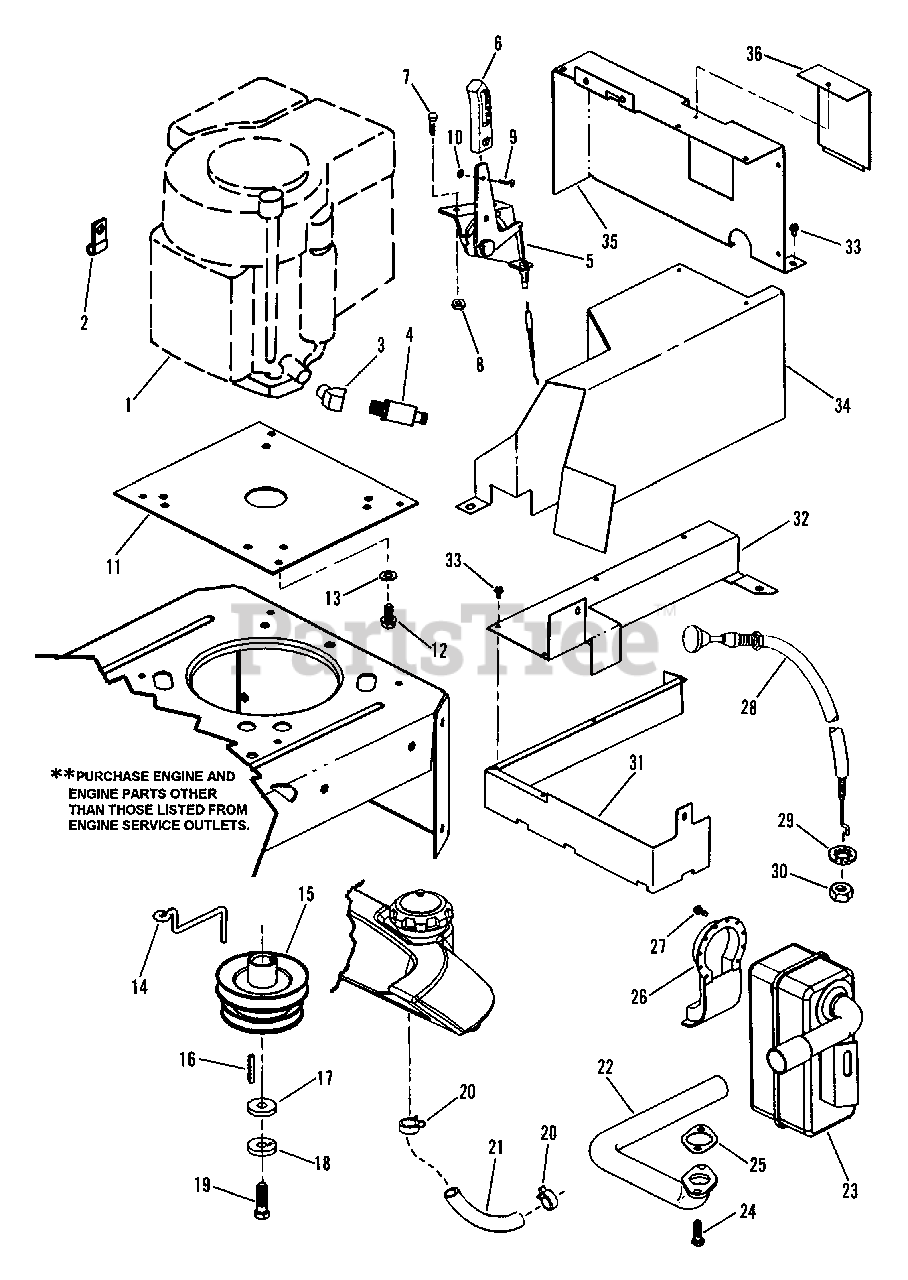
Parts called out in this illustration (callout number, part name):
2	WIRE CLIP, 7/16"
3	FITTING, Oil Drain 90° (Briggs 14HP)
4	ASSEMBLY, Oil Valve
5	CONTROL, Throttle (Kohler 15HP) 52.5"
6	LEVER, Throttle Control
7	SCREW, #10-32 x 5/8" Hex Washer Head, Grade 5
8	NUT, #10-32 Nyloc
9	SCREW, #8-32 x 3/8" Machine
10	NUT, #8-32 Hex
11	PLATE, Engine
12	SCREW,3/8-16 x1" Hex Washer Head (Briggs)
13	WASHER, 5/16 Split Lock (Kohler)
14	GUIDE, Belt
15	PULLEY, Engine (Small Pulley - Down)
16	KEY, 1/4" Square x 2"
17	SPACER, Clutch
18	WASHER, 7/16" Split Lock
19	SCREW, 7/16-20 x 1-1/2" Hex Head Cap, Grade 5
20	CLAMP, Fuel Hose
21	HOSE, Fuel 1/4" I.D.x 20"
22	PIPE, Exhaust (Briggs 14HP)
23	MUFFLER, Low Tone
24	SCREW, 5/16-18 x 3/4" Hex Head Cap, Grade 5 (Briggs 14HP)
25	GASKET, Exhaust (Briggs 14HP)
26	DEFLECTOR, Muffler (42" & 48" Decks only)
27	SCREW, #8-18 x 1/2" (42" & 48" Decks only)
28	CONTROL CABLE, Choke (Briggs 16HP & Kohler 15HP)
29	WASHER, 3/8" Internal Tooth Lock (Briggs 16HP & Kohler)
30	NUT, 3/8-24 Hex (Briggs 16HP & Kohler 15HP)
31	HEAT SHIELD, Sides (Kohler 15HP)
32	HEAT SHIELD, Top (Kohler 15HP)
33	SCREW, #10-32 x 3/8" Sheet Metal (Qty.4 Kohler, 8 Briggs)
34	DUCT, Right Hand (Briggs 14HP)
35	DUCT, Front (Briggs 14HP)
36	COVER, Spark Plug Access (Briggs 14HP)
